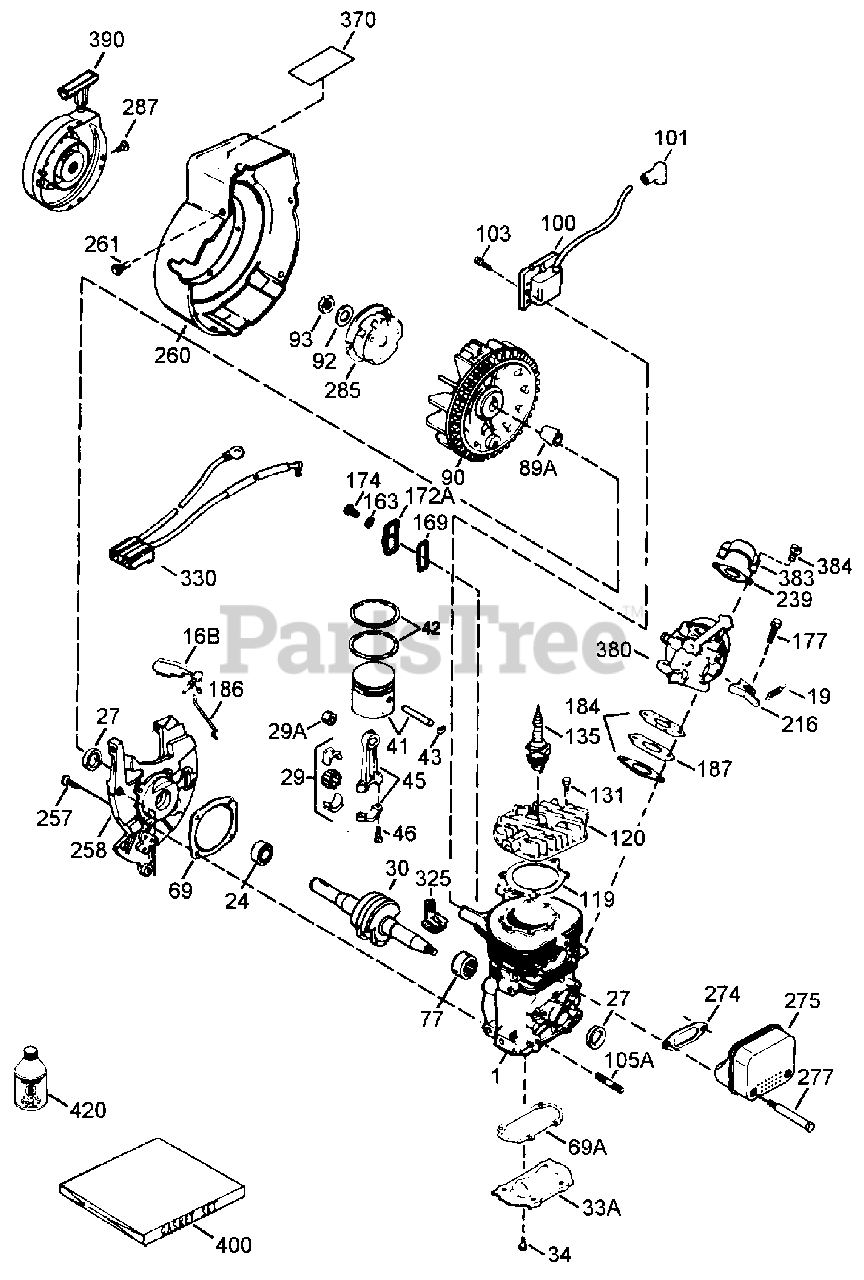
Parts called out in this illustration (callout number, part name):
1	Cylinder (Order Short Block if Replacement is needed)
16B	Air Vane
19	Extension Spring
24	Ball Bearing
27	Oil Seal
29	Needle Bearing & Liner Set (37 Needles)
29A	Cartridge Bearing
30	Crankshaft
33A	Cover Plate
34	Screw, Torx T-25
41	Piston & Pin Assembly
42	Ring Set
43	Piston Pin Retaining Ring
45	Connecting Rod Assembly (Incl. Ref. #29, 29A, & 46)
46	Connecting Rod Bolt
69	Cylinder Cover Gasket
69A	Cover Plate Gasket
77	Cartridge Bearing
89A	Adapter Sleeve
90	Flywheel
92	Belleville Washer
93	Flywheel Nutt
100	Solid State Ignition (Incl. Ref. #101)
101	Spark Plug Cover
103	Screw, Torx T-15
119	Cylinder Head Gasket
120	Cylinder Head
131	Screw, Torx T-30
135	Resistor Spark Plug
169	Cover Plate Gasket
172A	Compression Release Cover
174	Screw, Torx T-25
184	Carburetor Gasket
186	Governor Link
216	R.P.M. Adjusting Lever
239	Air Cleaner Gasket
257	Screw, Torx T-30
258	Blower Housing Base (Incl. Ref. #27)
260	Blower Housing
274	Exhaust Gasket
275	Muffler (Incl. Ref. #274 & 277)
285	Starter Cup
325	Wire Clip
330	Wire Harness
370	Instruction Decal
380	Carburetor (Incl. Ref. #184)
383	Spit Cup
384	Screw, Torx T-25
390	Rewind Starter
390	Rewind Starter NOTE: This engine could have been built with a 590735 starter. Refer to the design of the air intake louvers for part identifica-tion. Individual starter parts do not interchange.
400	Gasket Set
420	2-Cycle Oil (8 oz.)
